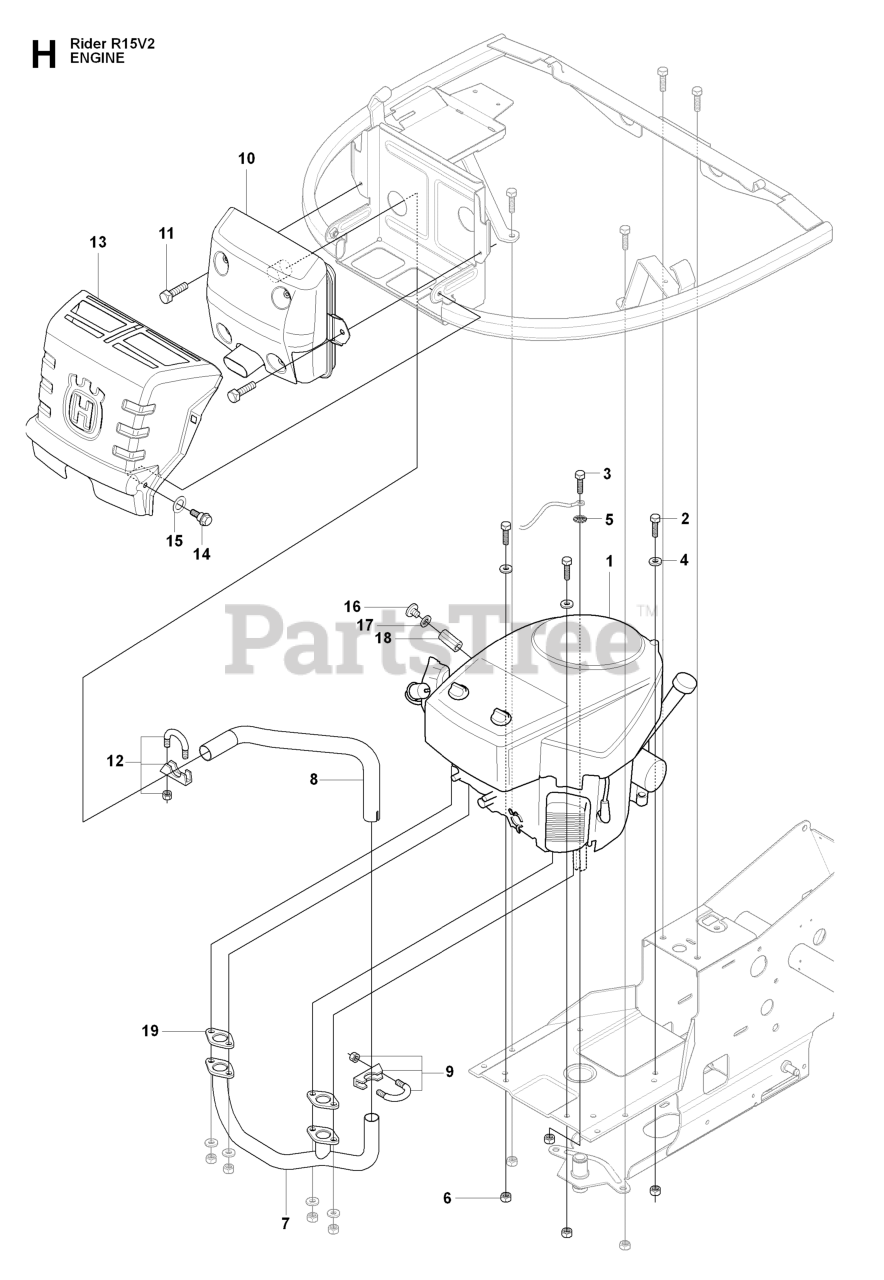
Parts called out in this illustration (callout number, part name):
4	WASHER BRB 8.4X17
6	LOCKNUT M8
8	PIPE KAWASAKI
9	CLAMP
12	CLAMP
13	HEAT PROTECTOR
15	SPRINGWASHER
